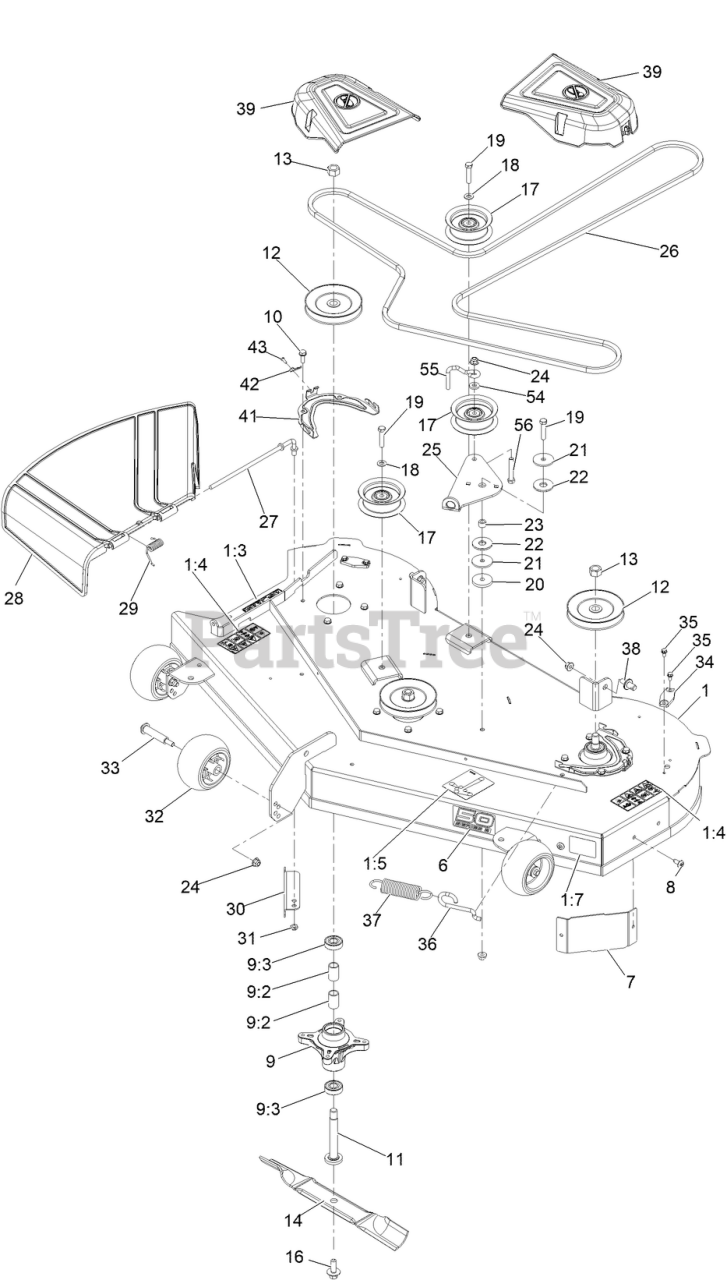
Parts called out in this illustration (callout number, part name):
1	50 INCH DECK AND DECAL ASM
1:3	Decal-Danger
1:4	DECAL-DANGER, DECK
1:5	DECAL-ROUTING, BELT
1:7	DECAL-SCALP, ANTI
6	Decal-50 Series 2
7	BAFFLE-CORNER
9	SPINDLE ASM
9:3	BEARING-BALL
10	SCREW-TAPTITE
11	SHAFT-SPINDLE
13	NUT-HEX
14	BLADE-HI LIFT
16	Bolt-Blade, Sems
17	PULLEY-IDLER, FLAT
18	WASHER-FLAT
19	SCREW-HH
20	WASHER-PLAIN
21	WASHER-REBOUND
22	WASHER-FRICTION, COMPOSIT
24	NUT-HF, NI
25	Arm-Idler
26	V-BELT
27	ROD-PIVOT
28	DEFLECTOR-DISCHARGE
29	SPRING-TORSION
30	BAFFLE-CUTOFF
32	ROLLER-SCALP, ANTI
33	BOLT-SHOULDER
34	COVER-WASHOUT PORT
35	SCREW-HWH
36	Hook-Return Spring
37	SPRING-EXTENSION
38	PIN-DECK
39	COVER-BELT
41	BRACKET-COVER, BELT
42	PIN-HAIR
54	SPACER-HUB, BLOWER
55	Belt Guide - Idler
56	SCREW-HH
